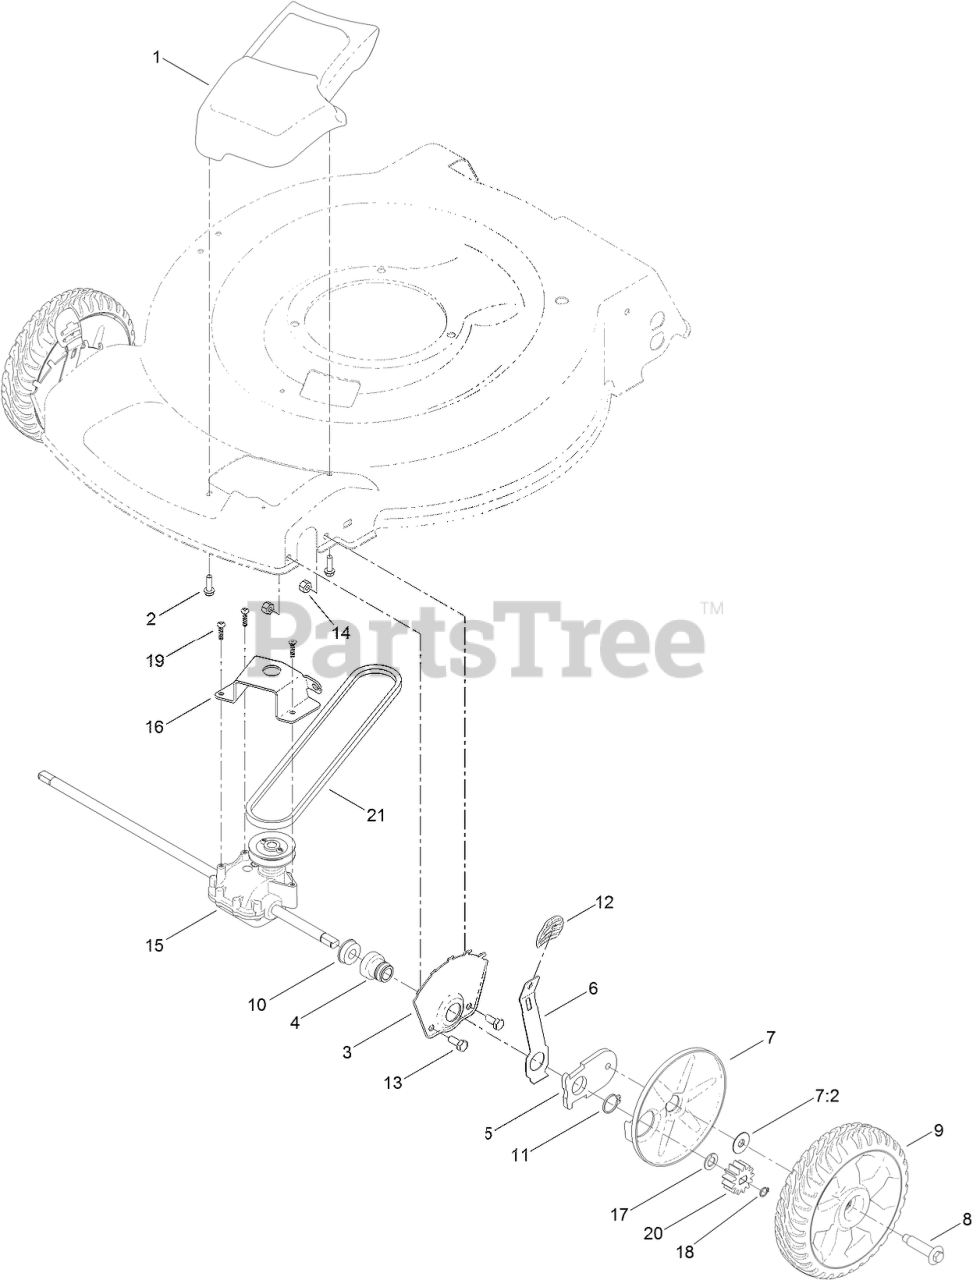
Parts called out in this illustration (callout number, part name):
1	COVER-BELT
2	SCREW-HWH
3	PLATE-HOC, FRONT
4	RETAINER-BEARING, HOC
5	ARM-PIVOT, FRONT
6	Arm-Spring
7	WHEEL COVER ASM
7:2	WASHER-STEPPED
8	BOLT-SHOULDER
9	8 INCH WHEEL ASM
10	BEARING-BALL
11	RING-RETAINING
12	Knob-Lever, HOC
13	SCREW-HH
14	NUT-LOCK, NI
15	TRANSMISSION ASM
16	BRACKET-TRANSMISSION
17	WASHER-THRUST
18	RING-RETAINING
19	SCREW-PLASTITE
20	GEAR-PINION, 13T
21	V-BELT
